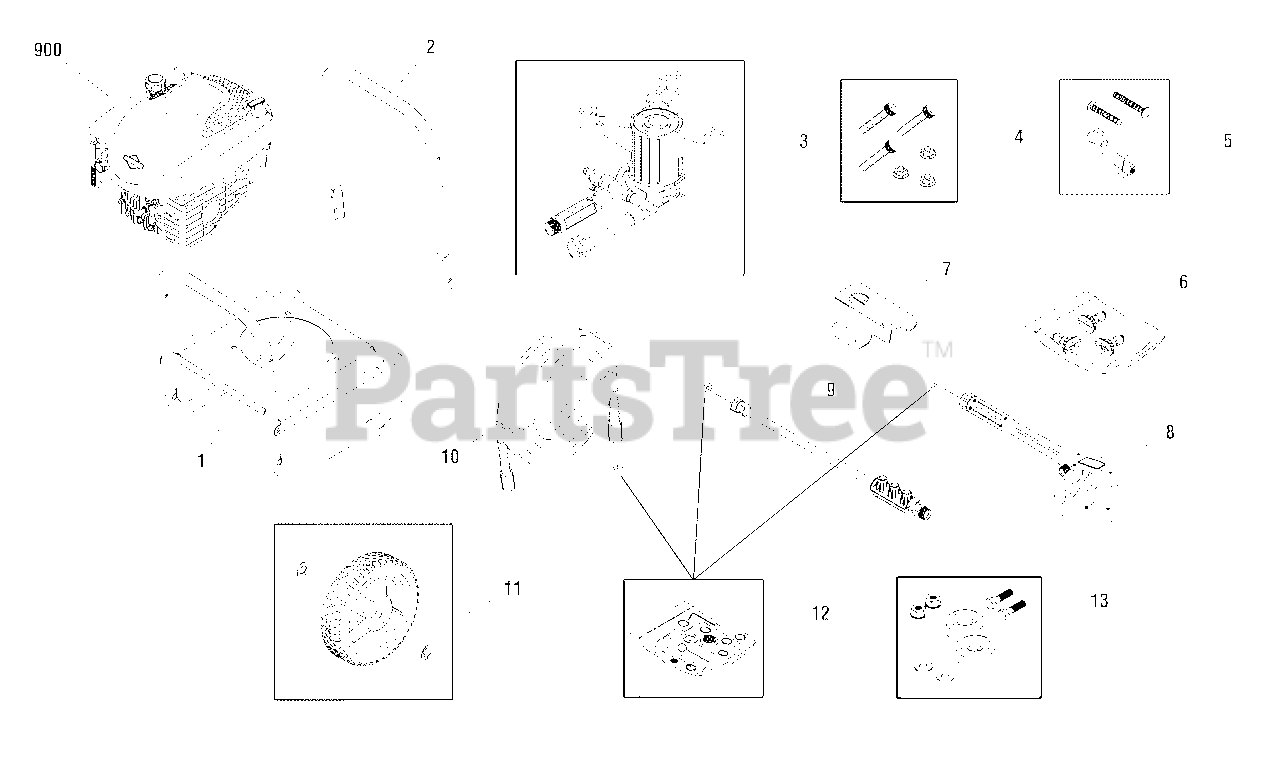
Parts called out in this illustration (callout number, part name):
2	HANDLE
3	PUMP
4	KIT, Hardware Pump Mounting
5	KIT, Hardware, Handle
7	HOLDER, Accessory
8	GUN
10	HOSE
12	KIT, O-Ring
13	KIT, Vibration Mount
900	* ENGINE
